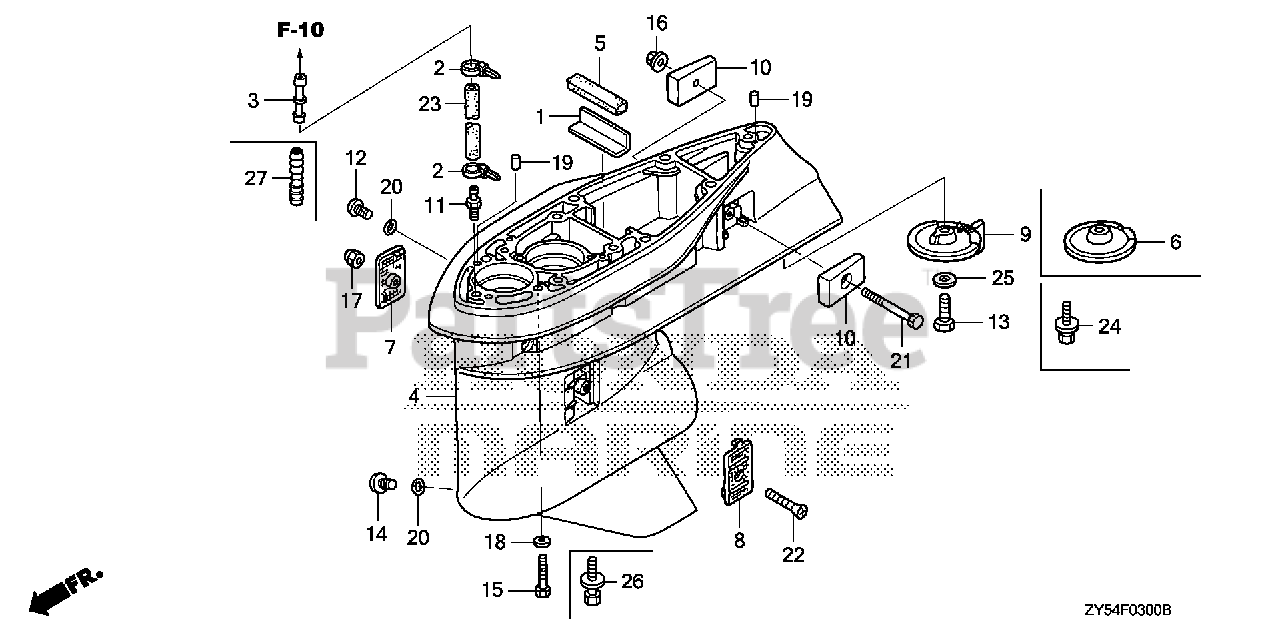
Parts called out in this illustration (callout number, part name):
1	PLATE, RUBBER SETTING
2	BAND, WIRE
3	JOINT B, WASHER TUBE (MITSUBA)
4	CASE, GEAR *NH282MU* (OYSTER SILVER METALLIC-U)
5	GROMMET, GEAR CASE
6	COVER,GE*NH282MU*
6	COVER, GEAR CASE *NH282MU* (OYSTER SILVER METALLIC-U)
7	SCREEN, R. WATER
8	SCREEN, L. WATER
10	METAL, ANODE
11	NIPPLE, SENSOR
12	BOLT, OIL CHECK
13	BOLT, HEX. (10X32)
14	BOLT, DRAIN PLUG
15	BOLT, HEX. (10X40)
16	NUT, SELF-LOCK (6MM)
17	NUT, SELF-LOCK (5MM)
18	WASHER, PLAIN (10MM)
19	PIN, DOWEL (6X10)
20	O-RING (6.9X1.45)
21	BOLT, HEX. (6X50)
22	SCREW, OVAL (5X50)
23	BULK HOSE, VACUUM (5X3000) (5X250)
24	BOLT-WASHER (10X32)
25	WASHER, PLAIN (10MM)
26	BOLT-WASHER (10X40)
27	END, NIPPLE
